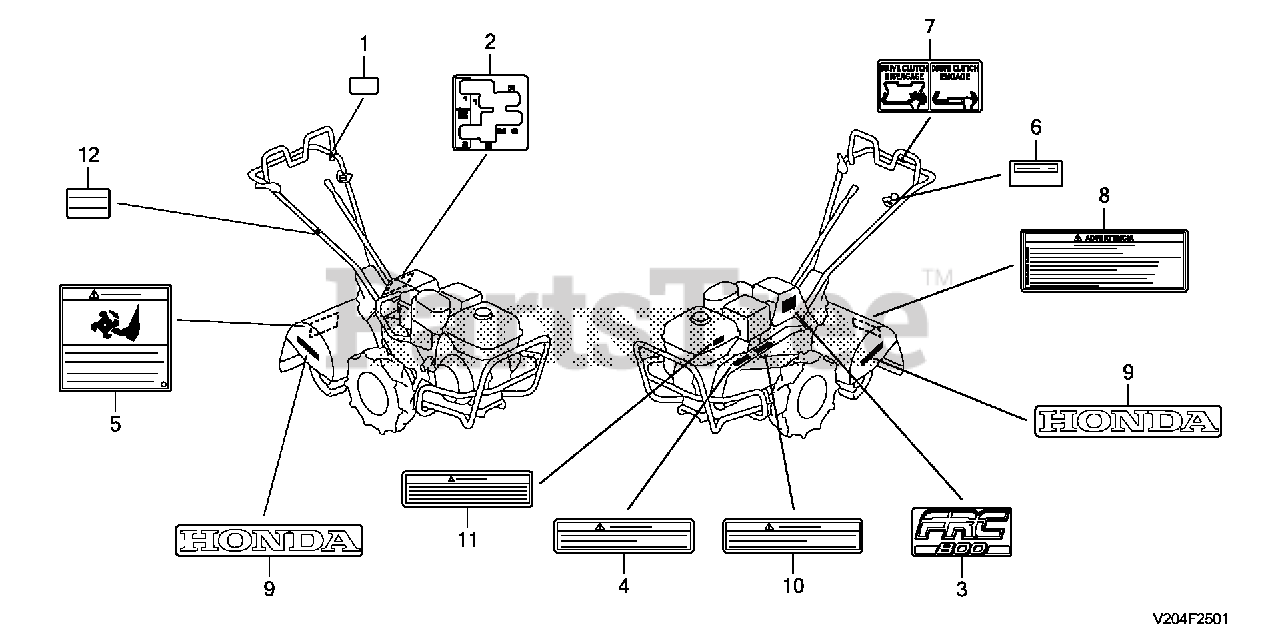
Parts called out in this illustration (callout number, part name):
1	SEAL, PROTECTOR (NOT AVAILABLE)
2	MARK, CHANGE (ENGLISH)
3	MARK, STRIPE
4	LABEL, BELT WARNING (ENGLISH)
5	LABEL, TINE DANGER (ENGLISH)
6	MARK, ENGINE SWITCH INDICATION
7	MARK, MAIN CLUTCH INDICATION
8	LABEL, OPERATOR WARNING (ENGLISH)
9	MARK, HONDA EMBLEM
10	LABEL, HEAT WARNING (ENGLISH)
11	LABEL, SPARK WARNING
12	MARK, HOLD POSITION
